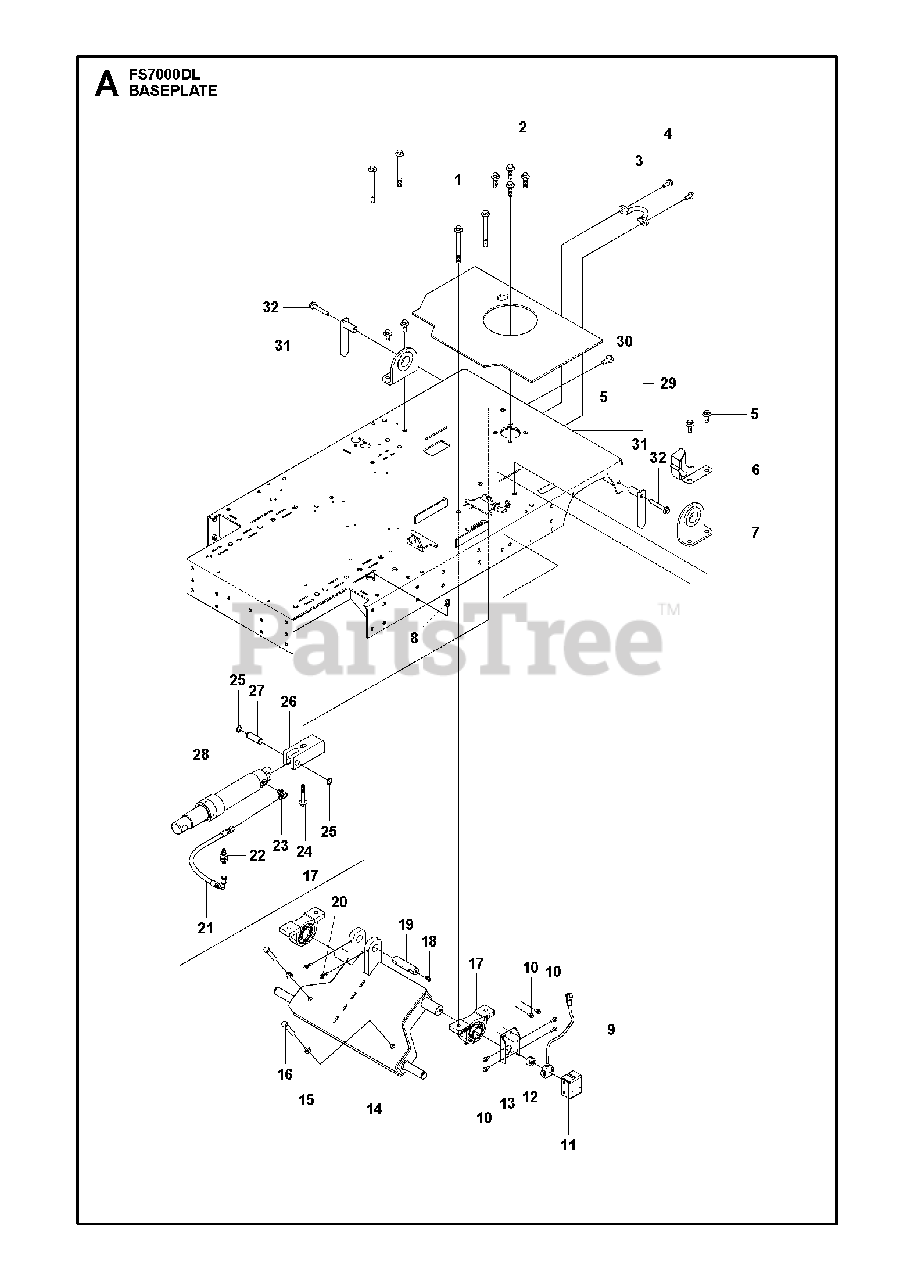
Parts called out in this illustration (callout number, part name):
14	FRONT AXLE36",42",48"
25	CIRCLIP
30	INSULATORInsulator included
